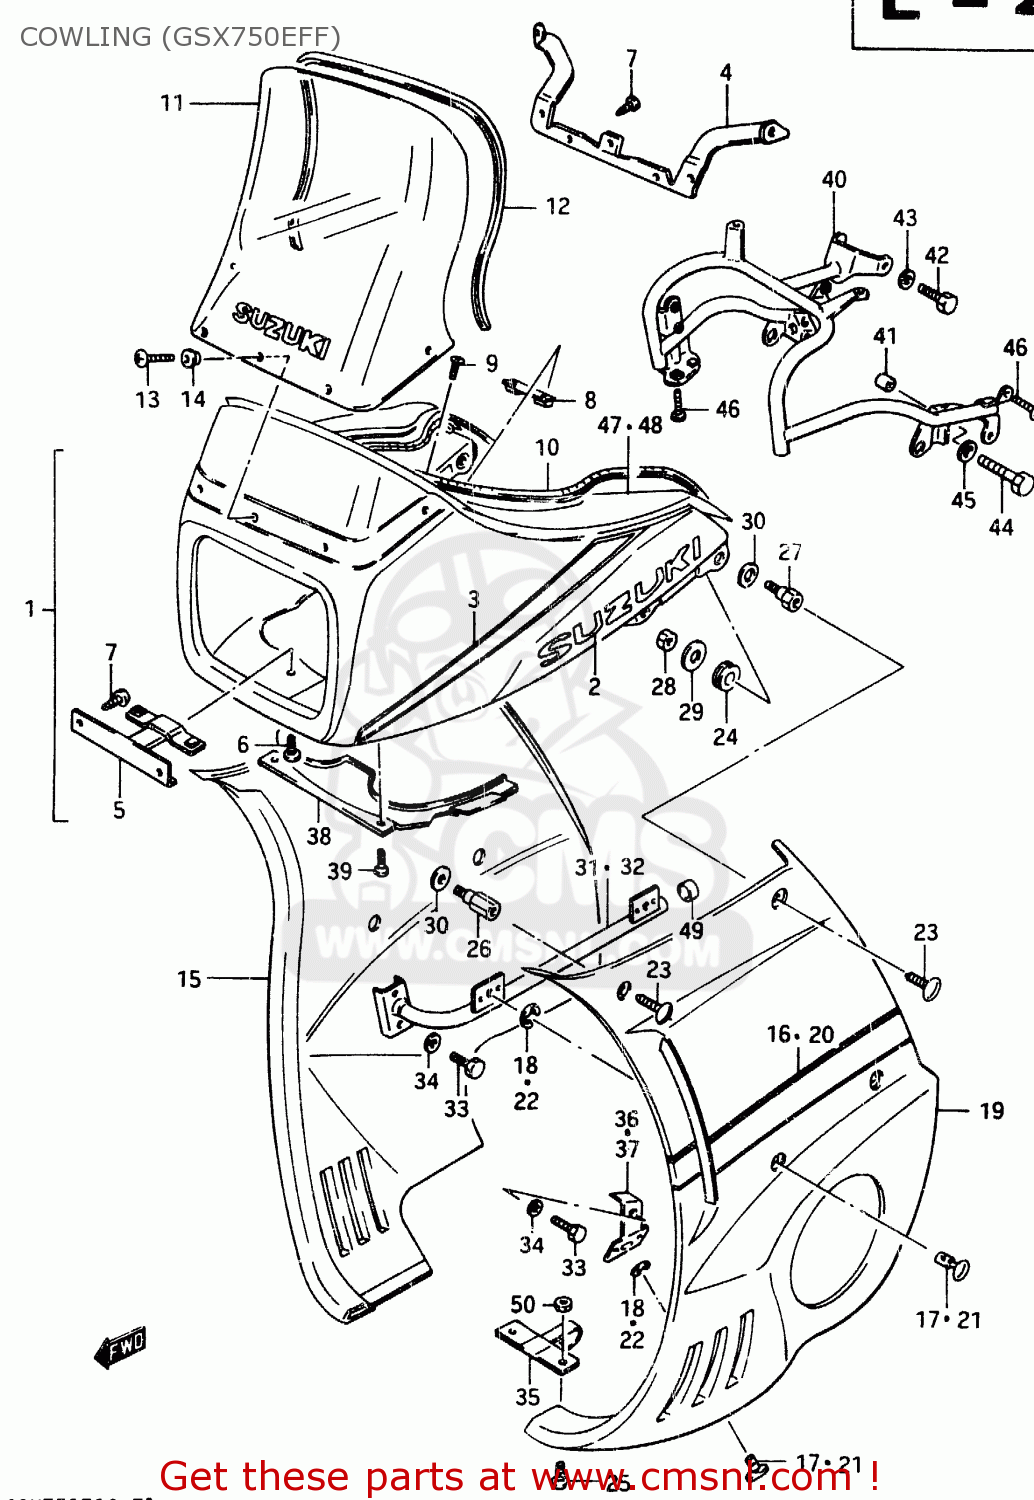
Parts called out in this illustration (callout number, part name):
1	COWLING ASSY (WHITE/RED)
2	EMBLEM
3	TAPE SET
4	BRACE,COWLING,UPPER
5	BRACE,COWLING,LOWER
6	SCREW
7	SCREW
8	BRACE
9	SCREW
10	MOLDING,FUEL TANK
11	WINDOW
12	MOLDING
13	SCREW
14	CUSHION
15	COVER, RH (WHITE/RED)
16	TAPE SET
17	FASTENER,COWL SIDE COVER
18	E-RING
19	COVER, LH (WHITE/RED)
20	TAPE SET
21	FASTENER,COWL SIDE COVER
22	E-RING
23	SCREW,COWLING SIDE COVER
24	CUSHION
25	SCREW 6X12
26	BOSS, FRONT
27	BOSS, REAR
28	NUT
29	WASHER (6.5X24X1.6)
30	WASHER
31	BRACE, RH
32	BRACE, LH
33	BOLT
34	WASHER,LOCK
35	BRACE, FRONT
36	BRACE, RH
37	BRACE, LH
38	COVER,COWLING,LOWER
39	SCREW
40	BRACE,COWLING
41	SPACER,COWLING
42	BOLT
43	WASHER,LOCK,8.
44	BOLT, LOWER
45	WASHER,LOCK,8.
46	SCREW 6X12
47	TAPE,RIGHT
48	TAPE,LEFT
49	CUSHION
50	NUT
